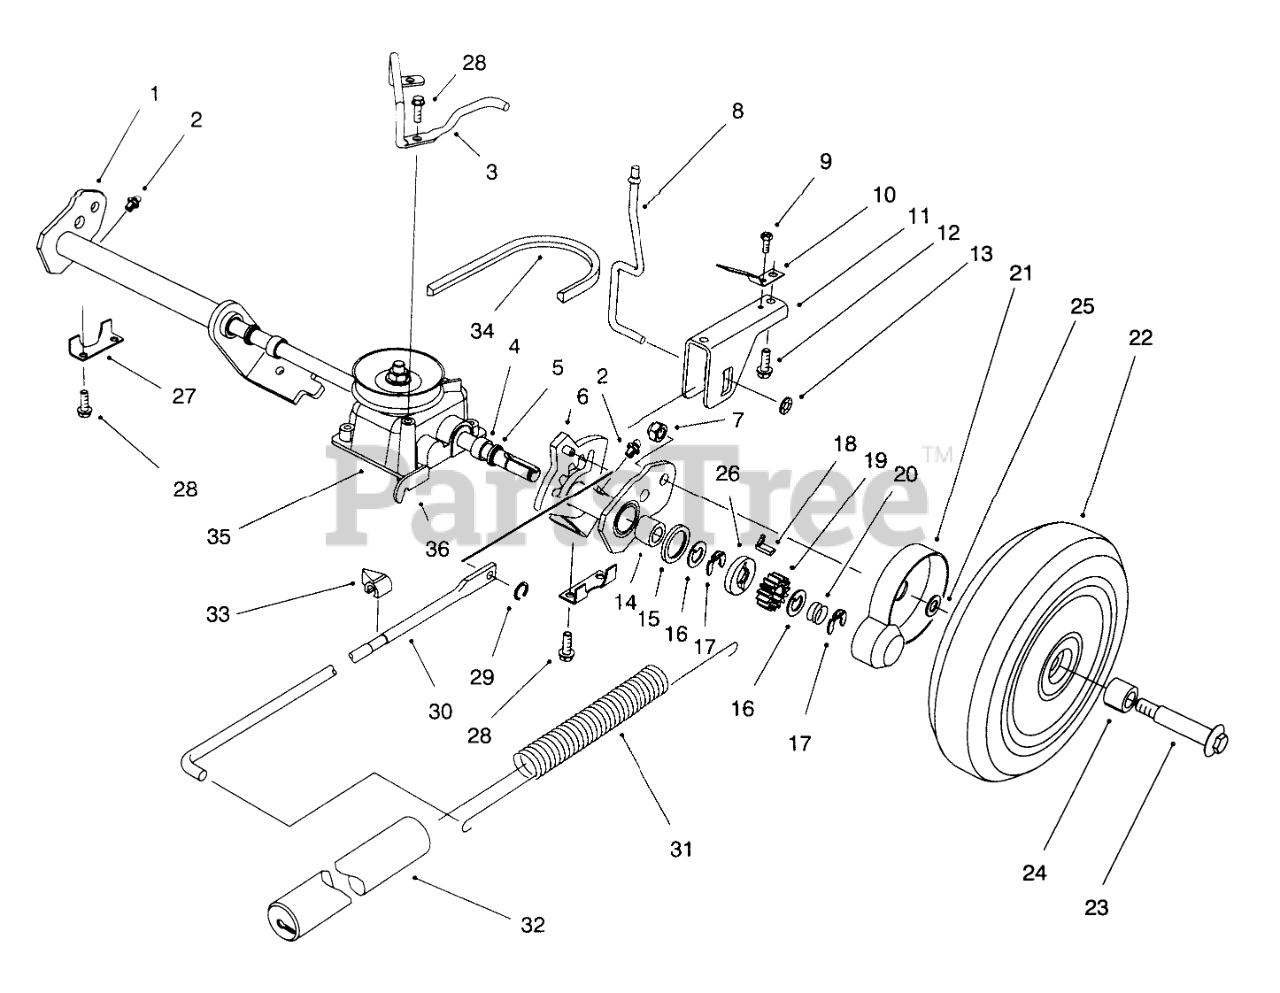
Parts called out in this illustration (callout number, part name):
1	Rear Pivot Assembly R.H. (Incl. Ref. #2, 4, 5 & 14)
2	FITTING-GREASE
3	Retainer Belt
4	BUSHING
5	SEAL-OIL
6	Rear Pivot Assembly L.H. (Incl. Ref. #2, 4, 5 & 14)
7	NUT-HEX
8	TRIGGER ROD
9	SCREW 8 - 32 X 250
10	SPRING - TRIGGER RET
11	SADDLE - HOC
12	SCREW
13	PUSHNUT
14	BEARING-ROLLER
15	RING-FRICTION
16	WASHER-THRUST, KEYED
17	RING-CLIP, LOCKING
18	KEY-ROCKING, LH
19	GEAR-PINION
20	SPRING-COMPRESSION
21	COVER-WHEEL
22	Wheel, Tire & Gear Assy. (Incl. Ref. #24)
23	BOLT-WHEEL
24	BUSHING
25	SPACER-COVER, WHEEL
26	WASHER-CLUTCH
27	REAR SECURING PLATE
28	SCREW-HWH
29	GRIP RING
30	LINK ROD
31	SPRING-COUNTERBALANCE
32	COVER-SPRING
33	INDICATOR-HEIGHT OF CUT
34	V-BELT
35	Gearcase Assembly (Incl. Ref. #36)
36	Bracket-Traction
